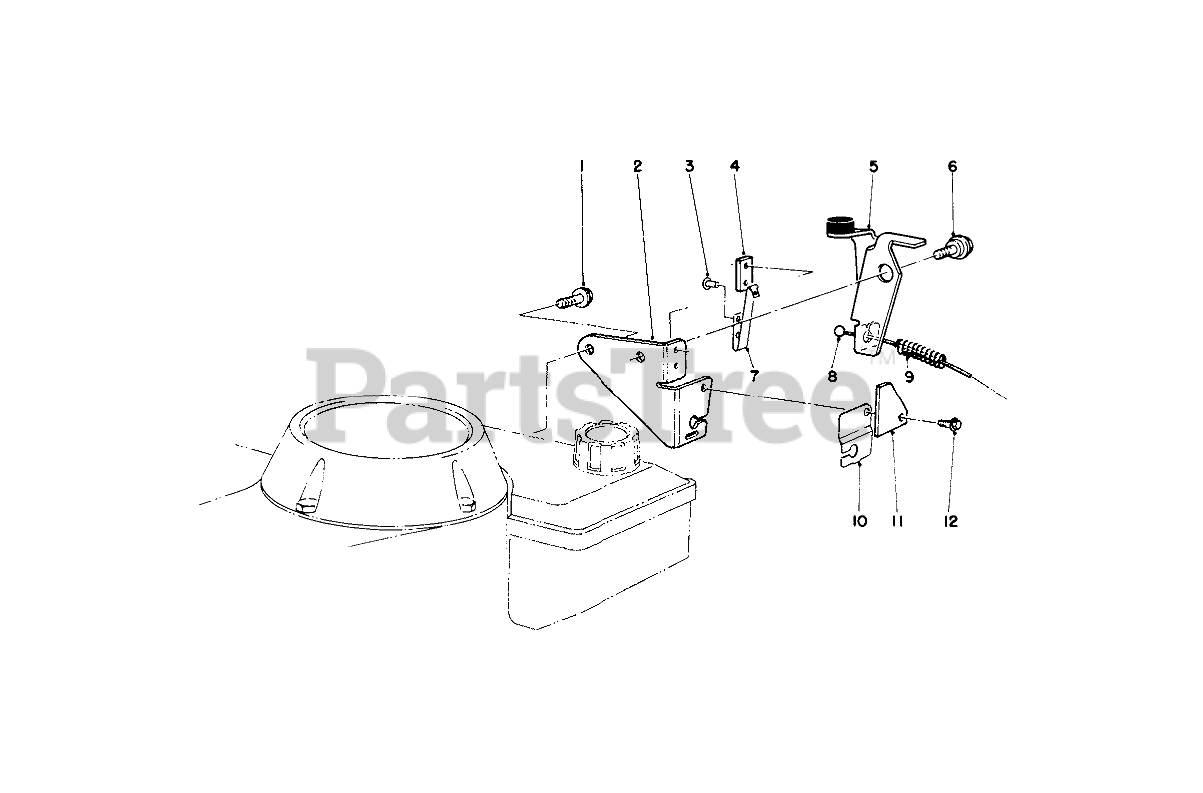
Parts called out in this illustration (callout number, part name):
1	THO FORM SCREW M6 X 1
2	Plate-Mounting
3	RIVET-PLASTIC
4	Strap-Insulation
5	BRAKE PLATE ASM
6	Screw-Shoulder
7	STRAP-GROUND
8	BRAKE CABLE
9	SPRING-COMPRESSION
10	CABLE CLAMP
11	STOP-GROUND STRAP
12	SCREW
